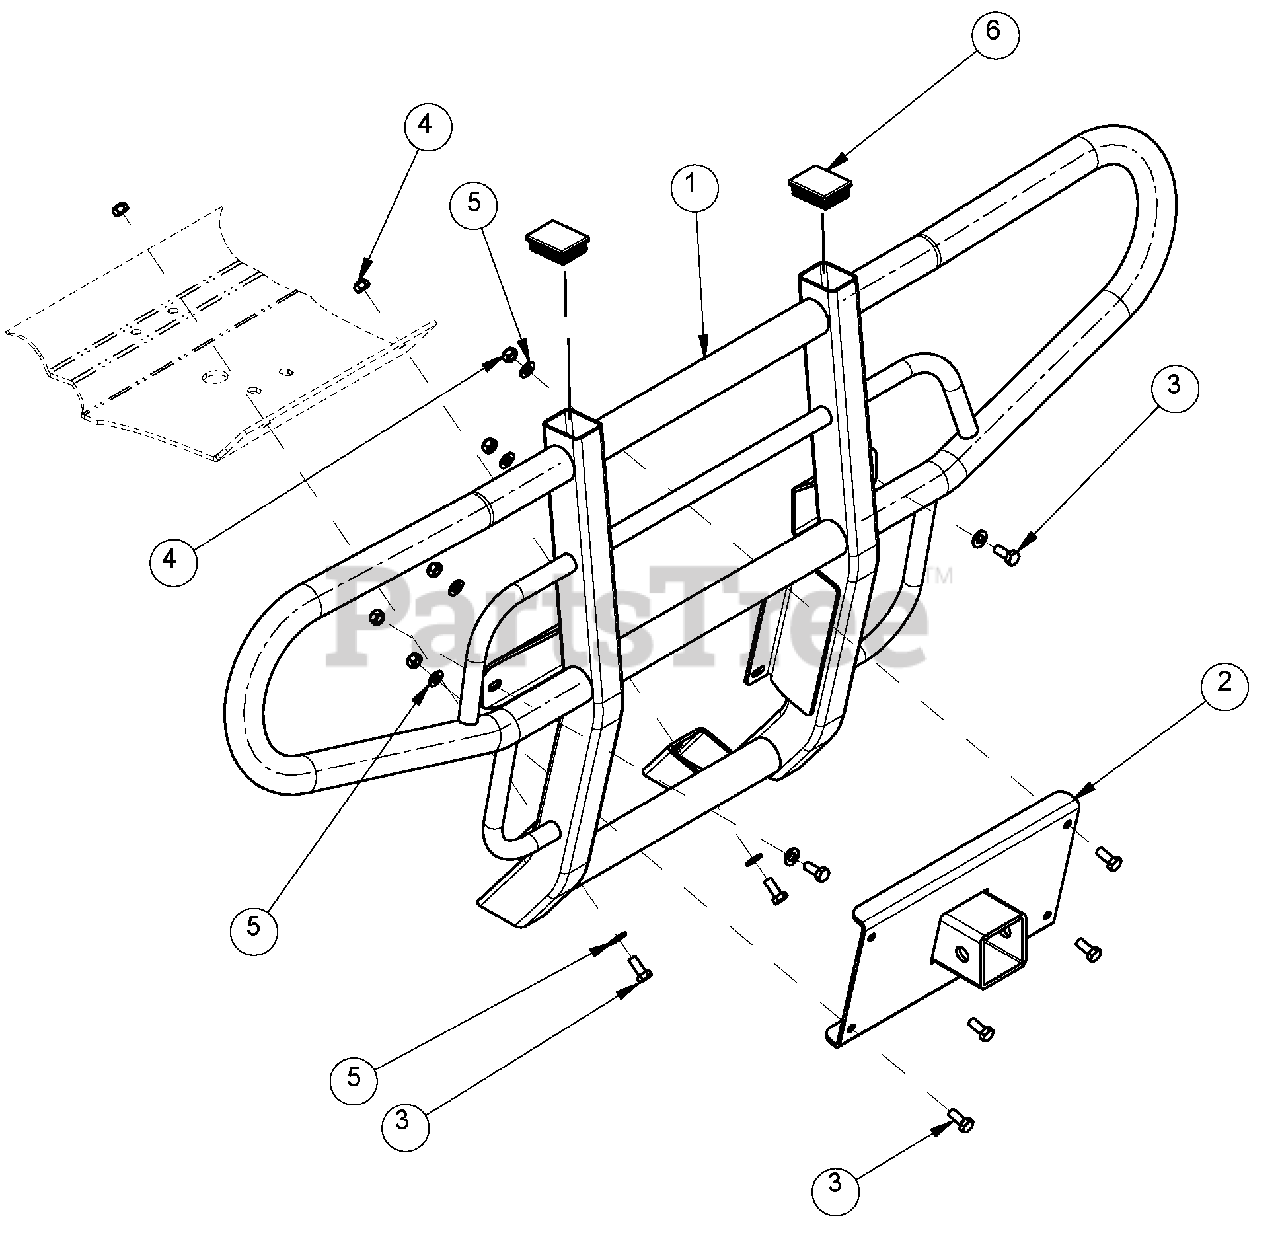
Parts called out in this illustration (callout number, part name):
1	BRUSH GUARD WLDMNT Optional
2	HITCH WELDMENT FRONT
3	BOLT, HEX 5/16-18X 3/4 GR5
4	NUT, NYLON LOCK 5/16-18
5	WASHER, FLAT 5/16 HARDENED ASTMF436
6	PLASTIC END CAP 2X1 1/2
